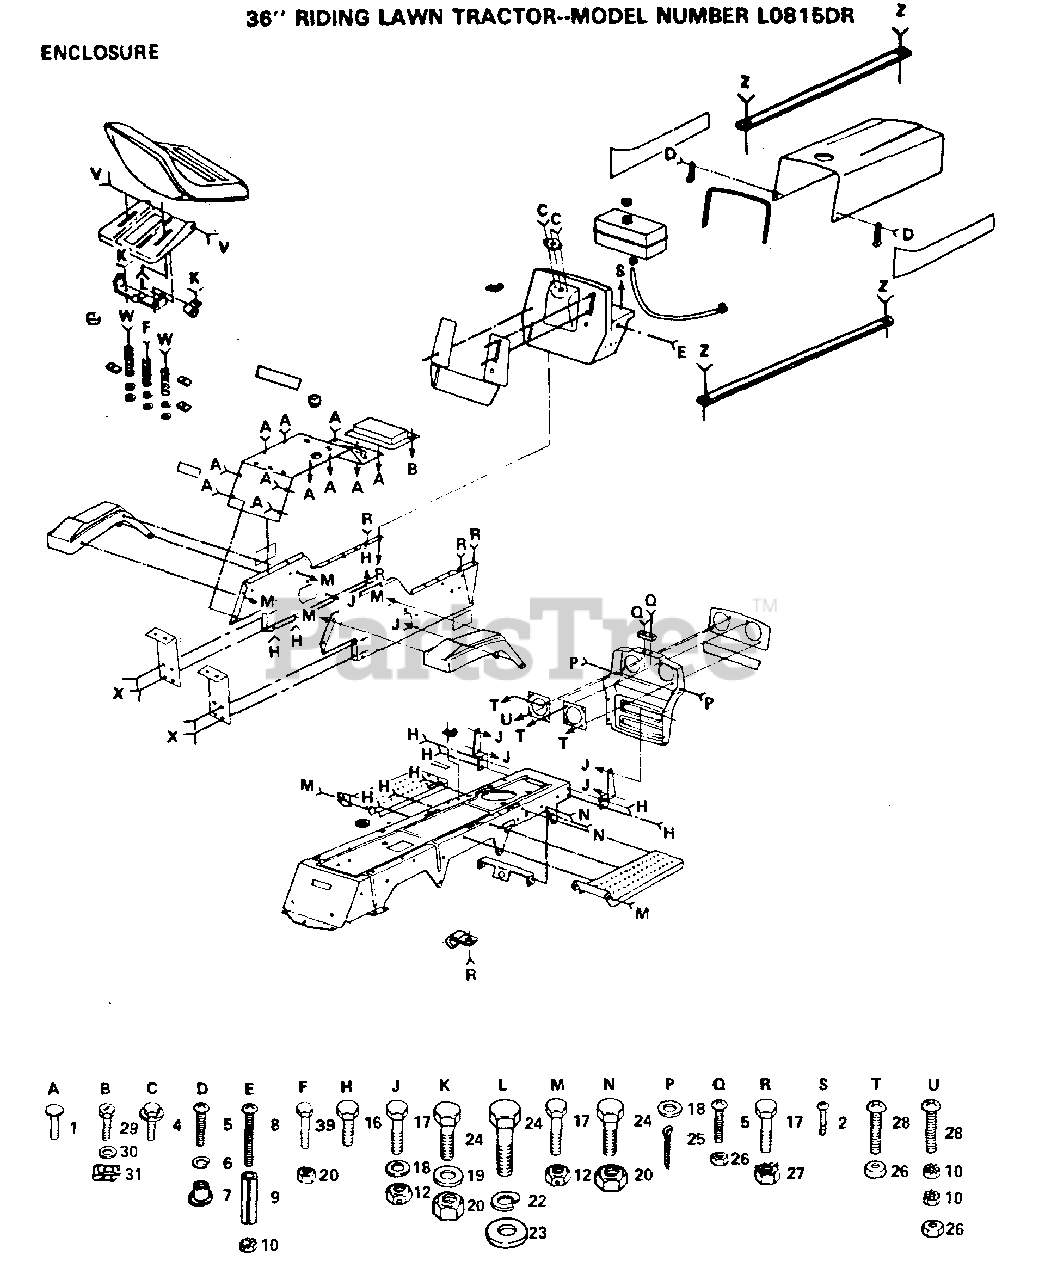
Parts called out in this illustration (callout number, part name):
5	CLIP SB
8	TANK.FUEL.LT
18	"PANEL LT, BATTE "
22	PANEL-SIDE LH LT
23	PANEL-SIDE RH LT
26	HOOD BUMPER
30	BRACKET-SUPP LT
32	CHANNEL ASSY
36	BRKT.ASM.SEAT.P
40	CLIP GTV
41	BRACKET-SUPP LT
43	FUEL LINE T
44	AXLE SUPPORT T
45	CLIP T
47	SEAT PAN T
49	"CLAMP, SPRING LT"
50	WASHER
53	SPRING T
55	CAP T
56	GROMMET T
